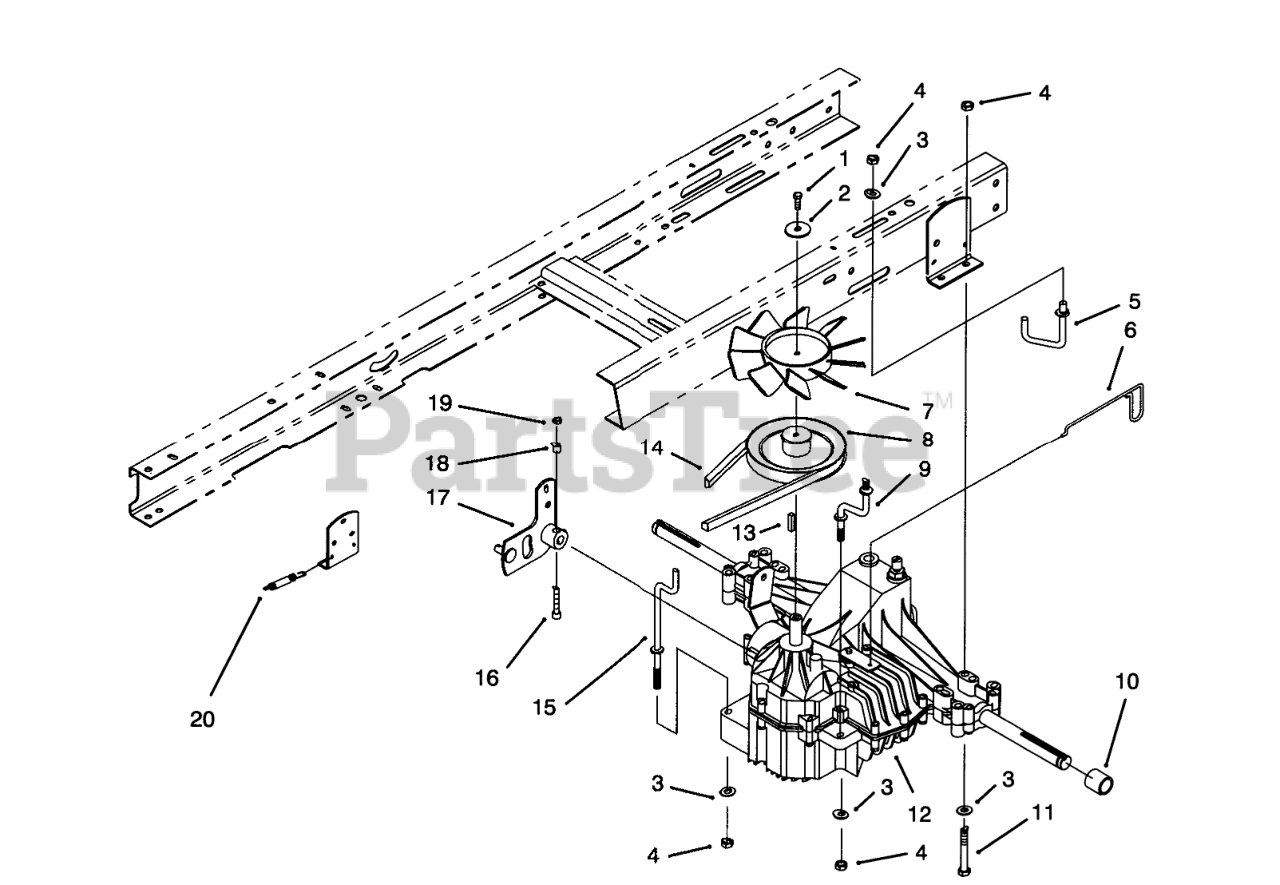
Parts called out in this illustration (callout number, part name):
1	SCREW-HH
2	WASHER-FLAT
3	WASHER-PLAIN
4	NUT-LOCK, NI
5	GUIDE-TRANS BELT, LH
6	ROD, DUMP VALVE
7	FAN-7"
8	HYDRO TRANS PULLEY
9	TORQUE STRAP
10	SPACER
11	SCREW-HH
12	TRANSAXLE ASM - HYDRO
13	KEY - 5MM SQUARE
14	V-BELT
15	RH TRANS BELT GUIDE
16	SCREW-HSH
17	SPEED CNTRL LEVER WA
18	LOCK SPACER
19	NUT-LOCK, NI
20	SPRING-RETURN, BRAKE
